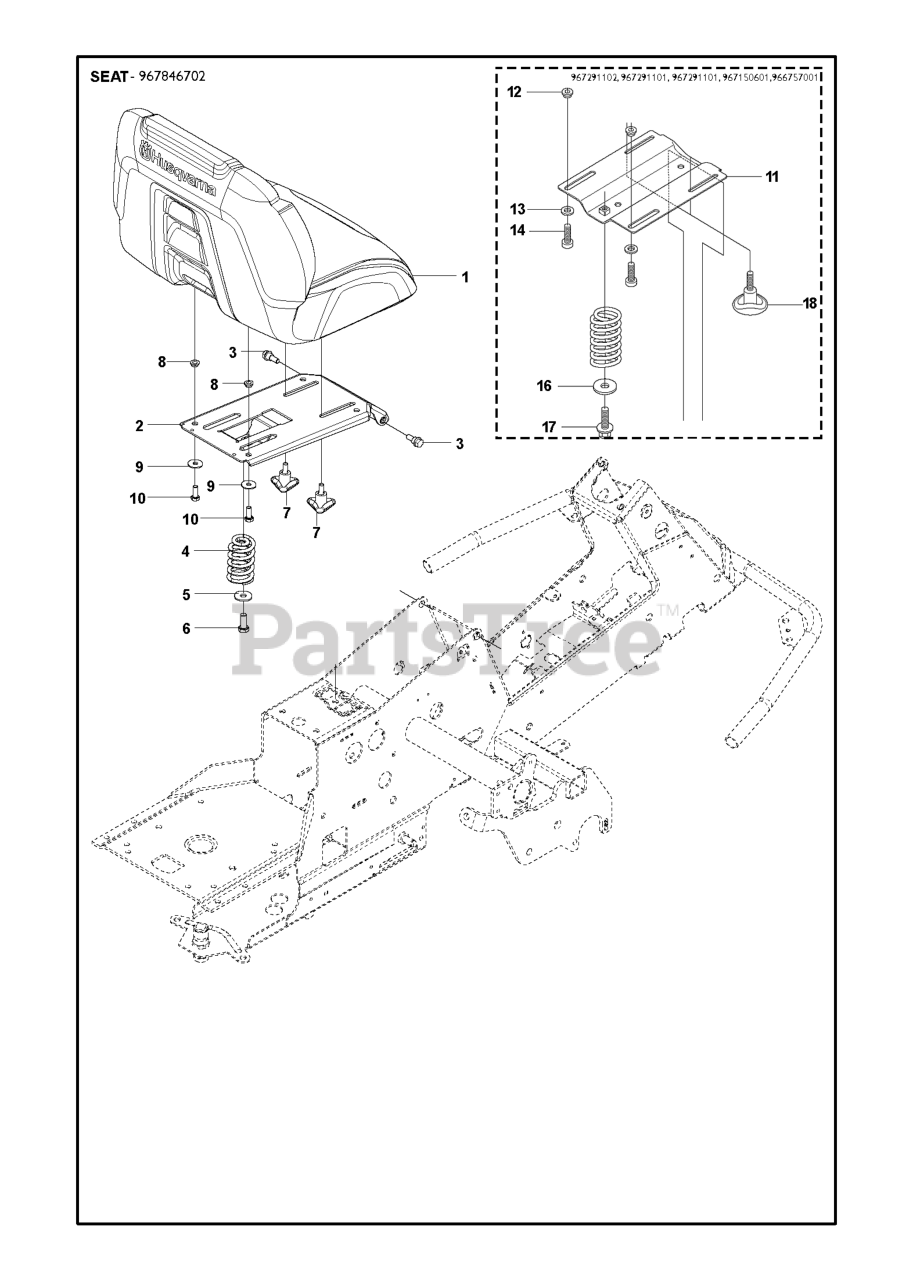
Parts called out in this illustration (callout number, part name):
1	SEAT HUSQVARNA LOW BACK
2	SEAT BRACKET ASSY
4	SEAT SPRING
6	Screw M10x25
11	SEAT BRACKET
12	WASHER
13	SPACER
14	SCREW
16	WASHER
17	Screw M10x25
18	KNOB M8
